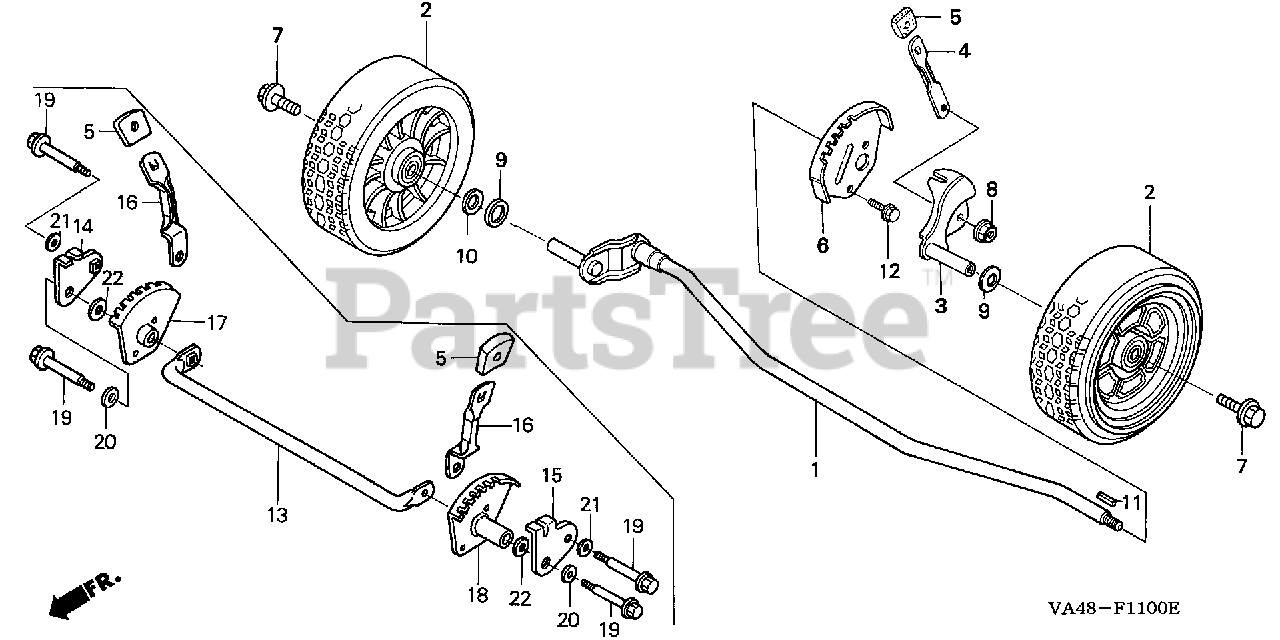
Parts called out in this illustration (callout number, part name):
1	SHAFT, FR. AXLE
2	WHEEL (8") *NH31* (MCKINLEY WHITE)
2	WHEEL (8") *NH166* (STANDARD GRAY)
3	ARM, L. FR. ADJUSTER
4	PLATE, FR. ADJUSTER
5	GRIP, ADJUSTER
6	PANEL, FR. ADJUSTER
7	BOLT, WHEEL
8	NUT, SELF-LOCK (8MM)
9	WASHER, WHEEL
10	WASHER, PLAIN (19.2X24)
11	KEY (4X4X11)
12	BOLT, FLANGE (6X12) Use up to Engine SN 1543277.
NI	TIRE (8 INCH)
